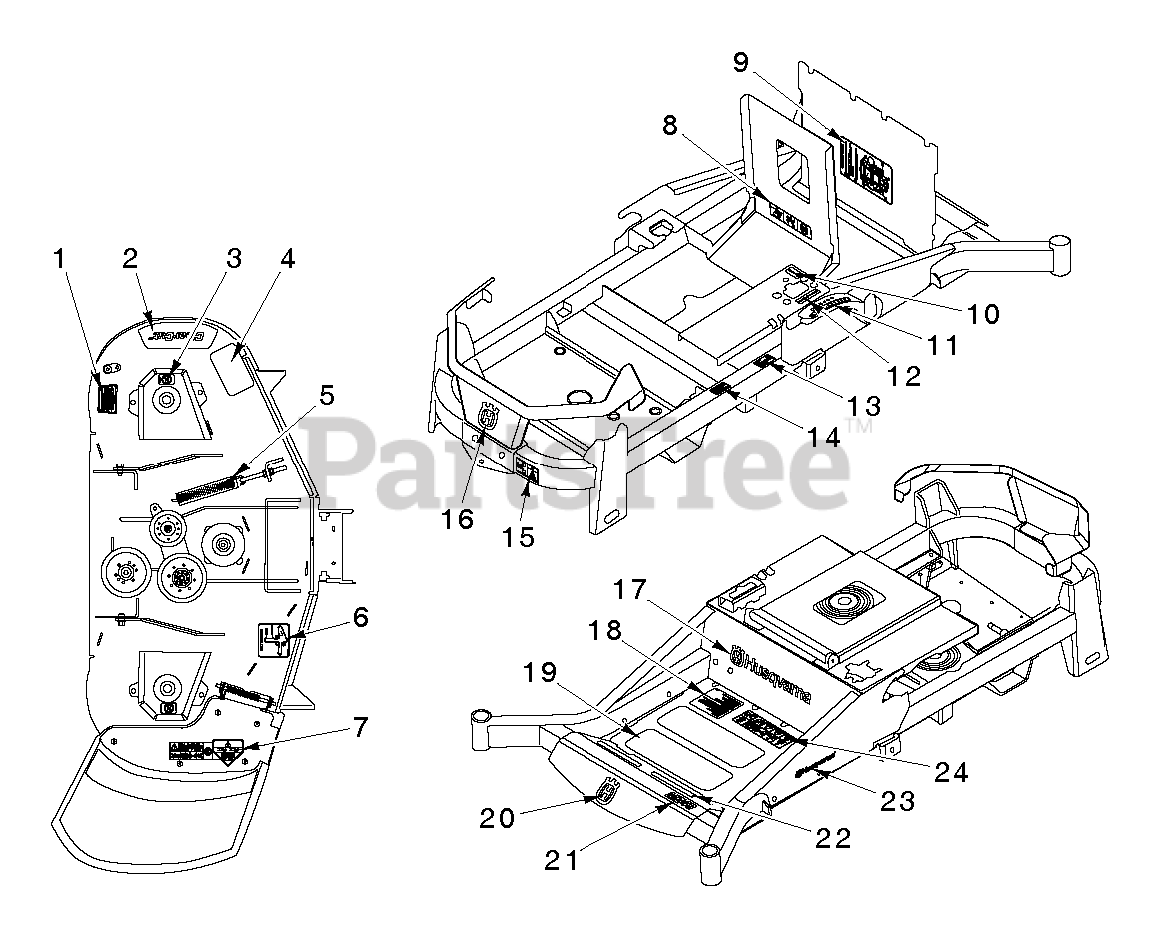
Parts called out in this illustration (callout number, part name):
1	DECAL DECK DECAL DECAL.DECK.WA
2	DECAL DECK DECAL DECAL.48DECK.
3	DECAL.DECK.CLEARCUT.NOSTEP
5	VIBRATION PAD
6	DECAL, BELT ROUTING
7	DECAL.TRACT/ZTR.DECKWARN.HUSQ
8	EURO DECAL-BATTERY WARNIN6
9	DECAL, SERVICE
10	DECAL.STR.S.T.SYSMBOLONLY.2014
11	DECAL, HEIGHT ADJUST
12	DECAL.ZTR.MOTCONTRL.SYMBOL.HUS
15	DECAL, BELT DRIVE
16	DECAL, CROWN H, 110MM
17	DECAL ZTR BRAND GRAPHIC DECAL.
18	DECAL.ZTR.STRTNGINST.REMOTECHK
19	ANTI-SKID PAD
20	DECAL.AUGER.HUSQ.CROWN.SNOW
21	DECAL.MZ48
23	RP.DECAL.BADGE.170MM.TEXTLOGO
24	DECAL ZTR WARNING DECAL DECAL.
